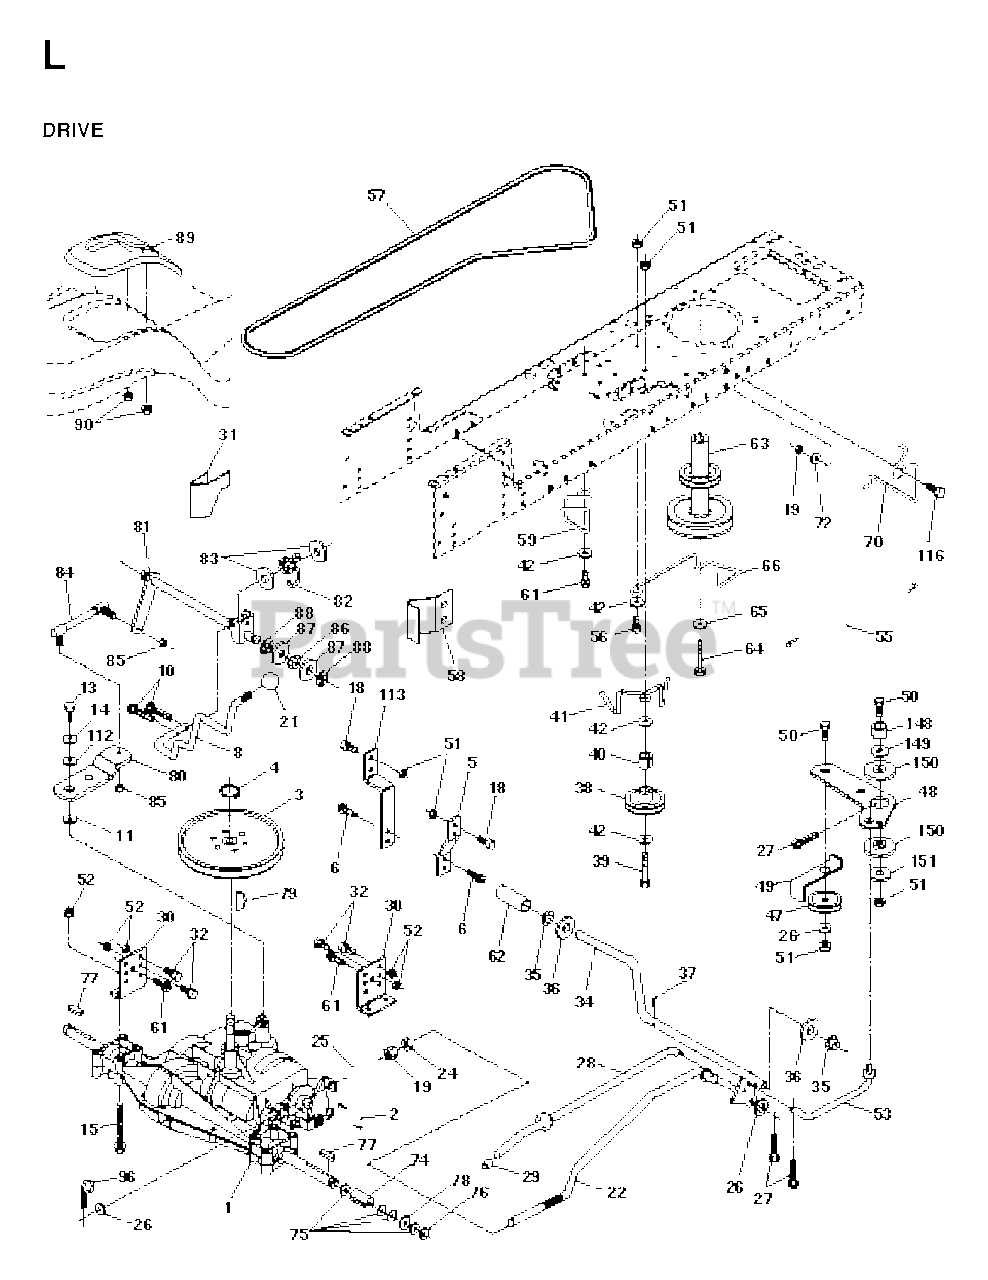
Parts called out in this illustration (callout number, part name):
2	SPRING,BRAKE RETURN
3	PULLEY TRANS
4	RETAINING RING LT
5	STRAP TORQUE
6	SCREW
8	ROD SHIFT FENDER
10	PIN COTTER
11	WASH-SHFT PLT LT
13	BOLT 1/4-28X3/4
14	LOCKWASHER
15	BOLT HEX 5/16-18 GR 5
19	NUT
21	KNOB.DELUXE.(PISTOL.GRIP).BLAC
22	ROD BRAKE
24	NUT
25	SPRING ROD LT
27	COTTER PIN
28	ROD BRAKE PARK LT
29	PLUNGER CAP
30	BRACKET TRANSAXLE
31	KEEPER BELT LH
32	BOLT
34	SHAFT, FOOT PEDAL
35	BEARING.NYLON
36	WASHER LT
37	DRIVE PIN
38	PULLEY.IDLER.FLAT
41	KEEPER, BELT IDLER
42	WASHER
47	IDLER PULLEY
48	BELLCRANK, CLUTCH
49	RETAIN BELT
50	BOLT
51	LOCKNUT
52	LOCKNUT
53	LINK, CLUTCH LT
55	SPRING, RETURN LT
59	KEEPER CENTER SPAN
61	SCREW
62	PEDAL COVER T
63	PULLEY ENGINE
64	BOLT
65	LOCKWASHER
66	KEEPER BELT ENGINE
70	KEEPER BELT ENG
74	SPACER AXLE
76	E-RING LT
77	SQUARE KEY
80	ARM SHIFT
82	SPRING,TORSION
83	WASHER
84	ROD,TIE
85	NUT LOCK CENTER 1/4 -28 FNTHD
88	KLIP RING
89	SHIFT CONSOLE
96	RETAINER M
112	WASHER LT
113	STRAP TORQUE LH LT
116	BOLT
148	GUIDE
149	SPACER RETAINER
150	BUSHING NYLON COLLERED
151	WASHER 12/32X2X10GA
